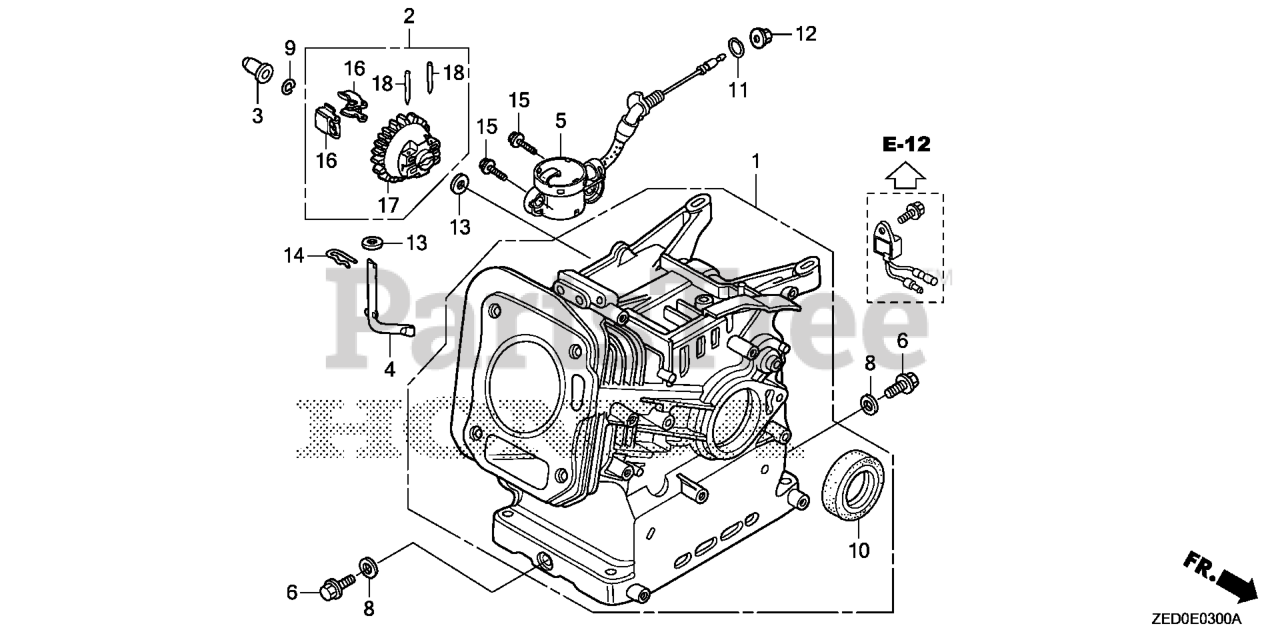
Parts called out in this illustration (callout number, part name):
1	CYLINDER ASSY. (OIL ALERT)
2	GOVERNOR ASSY.
3	SLIDER, GOVERNOR
4	SHAFT, GOVERNOR ARM
5	SWITCH ASSY., OIL LEVEL
6	BOLT, DRAIN PLUG
7	WASHER, THRUST (6MM)
8	WASHER, DRAIN PLUG (10.2MM)
9	CLIP, GOVERNOR HOLDER
10	OIL SEAL (25X41X6)
10	OIL SEAL (25X41X6) (ARAI) (NOT AVAILABLE)
11	O-RING (14MM)
11	O-RING (14MM) (ARAI) Use up to Engine SN 2949254.
12	NUT, FLANGE (10MM)
13	WASHER, PLAIN (6MM)
14	PIN, LOCK (8MM)
15	BOLT, FLANGE (6X12) Use up to Engine SN 1543277.
16	WEIGHT, GOVERNOR
17	HOLDER, GOVERNOR WEIGHT
18	PIN, GOVERNOR WEIGHT
